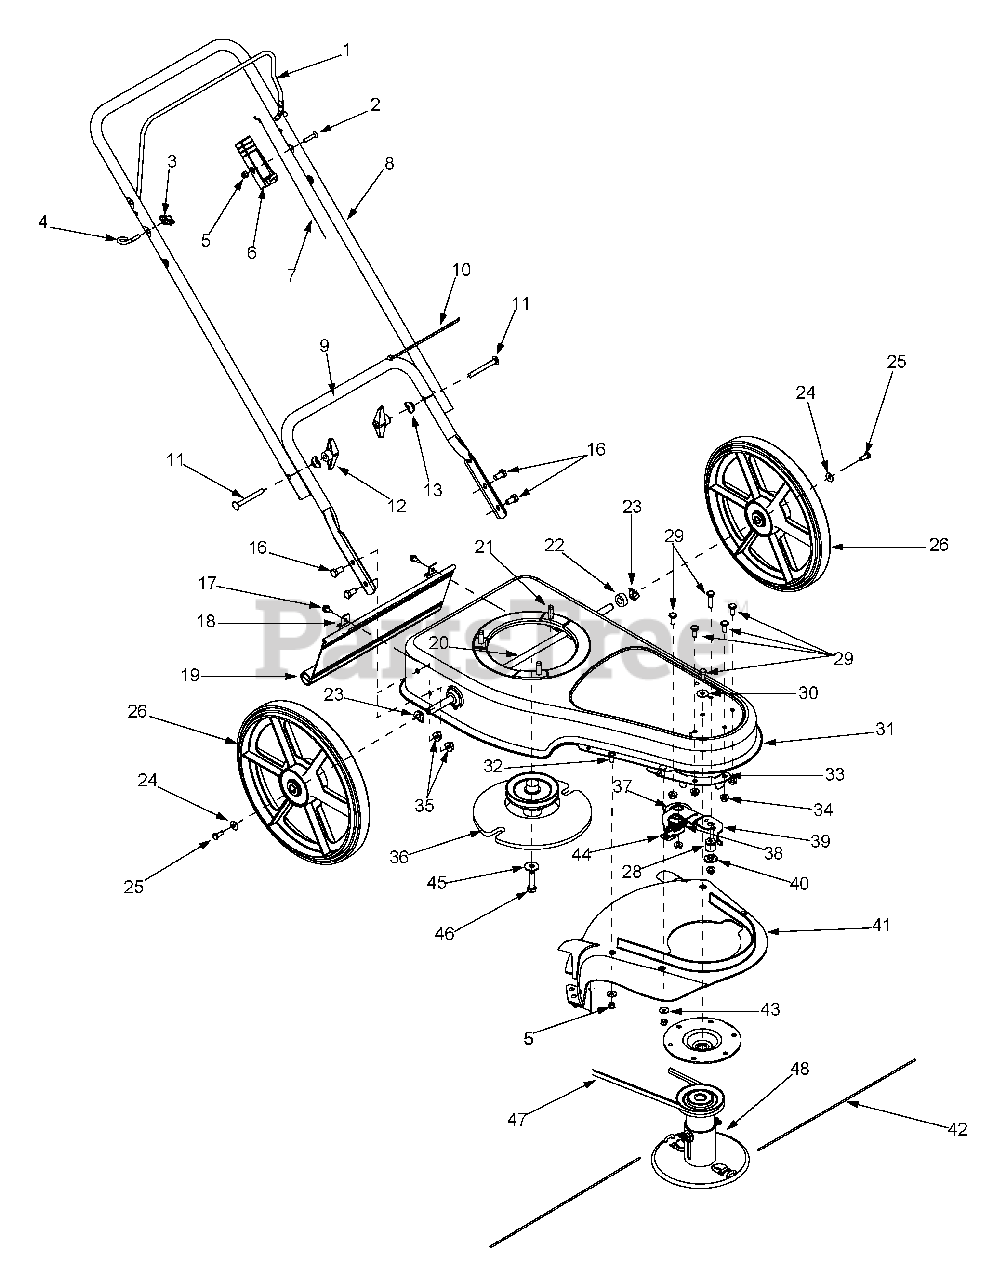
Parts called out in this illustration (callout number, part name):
3	Knob 1/4-20
4	Eye Bolt 1/4-20
5	Hex Lock Nut
6	Throttle Housing
7	Throttle Cable
11	Carriage Screw 5/16-18 x 2.0
12	Wing Nut 5/16-18
13	Saddle Washer.320 ID x.93 OD
16	Hex Cap Screw 3/8-16 x.750
17	Hex Washer Screw 1/4-20 x.625
18	Trail Shield Clip
19	Trail Shield
20	Axle Assembly
21	Hex Washer Screw 3/8-16 x.250
22	Spacer.51 ID x 1.00 OD x.38
23	Spring Washer.50 ID x 1.0 OD
24	Bell Washer.265 ID x.75 OD
25	Hex Cap Screw 1/4-20 x.75
26	Wheel 14 x 1.8 Bar Gray
28	P/M Spacer
29	Hex Cap Screw 5/16-24 x.625
30	Bell Washer.325 ID x.930 OD
34	Flange Lock Nut 5/16-18
35	Flange L-Nut 3/8-16
36	Flywheel Pulley
37	Idler Pulley
38	Extension Spring.50 ID x 3.375
39	Idler Bracket Assembly
40	Idler Spacer
41	Trimmer Deflector Assembly
42	Trimmer Line.130 Dia
43	Flat Washer.28 ID x.74 OD
45	Bell Washer.396 ID x 1.140 OD
46	Hex Cap Screw 3/8-24 x 1.50
47	V-Belt
48	Spindle Assembly, includes 782-0143
